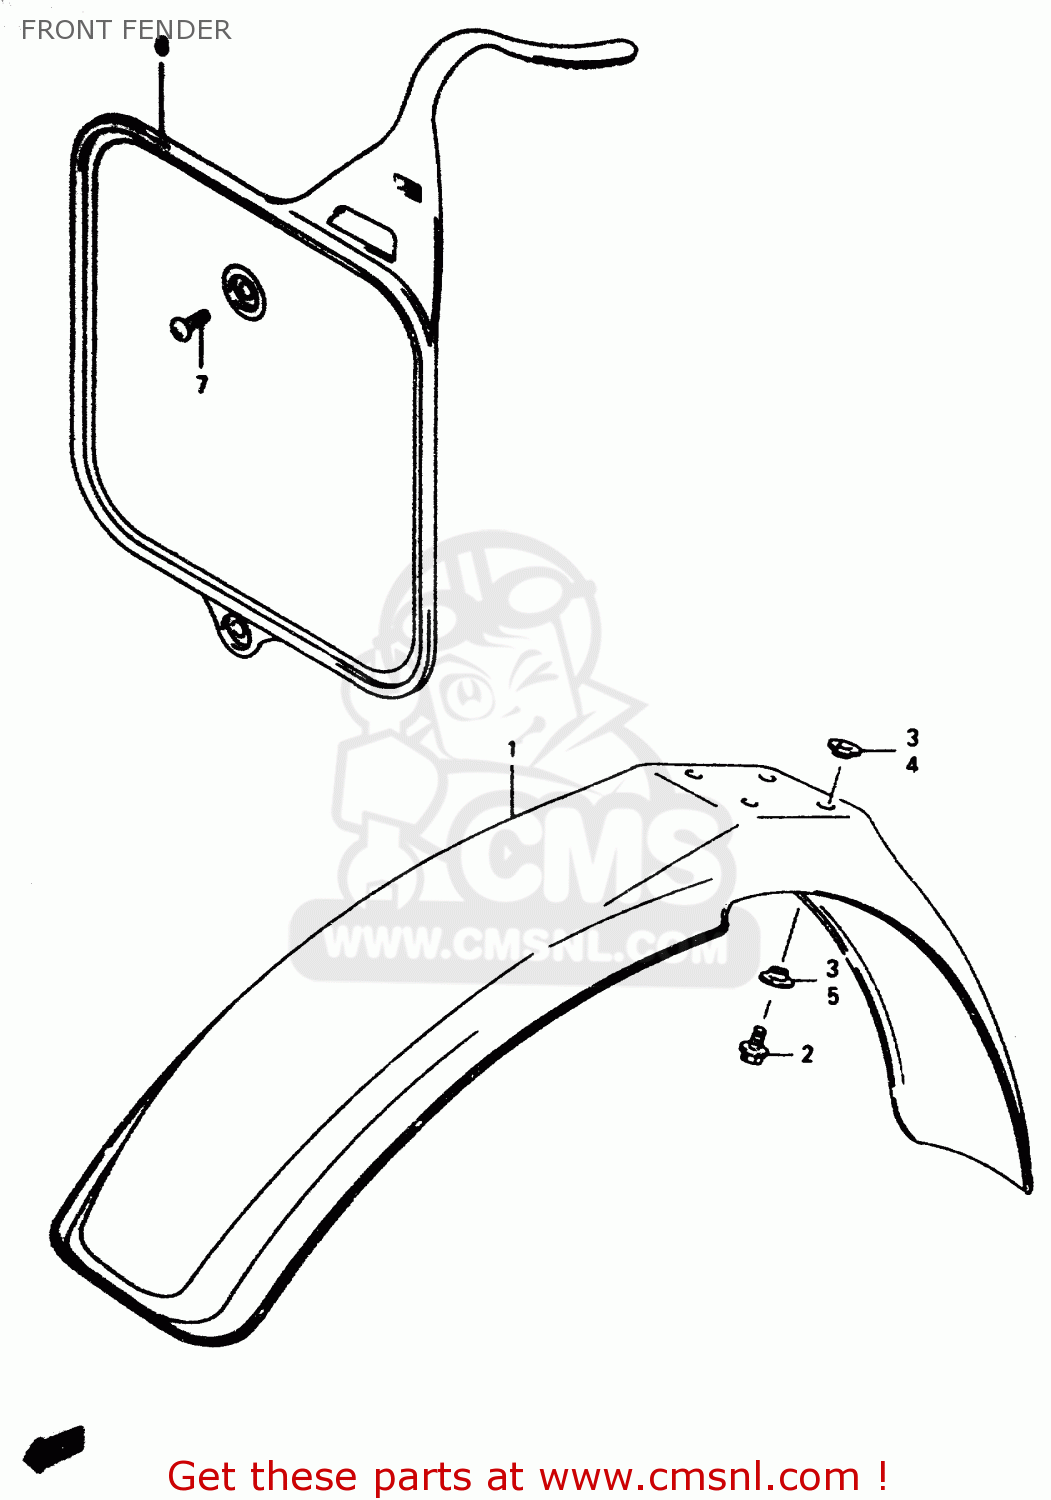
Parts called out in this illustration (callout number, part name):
1	FENDER,FRONT
2	BOLT
3	WASHER
4	WASHER
5	WASHER
6	PLATE,NUMBER FR
7	SCREW
